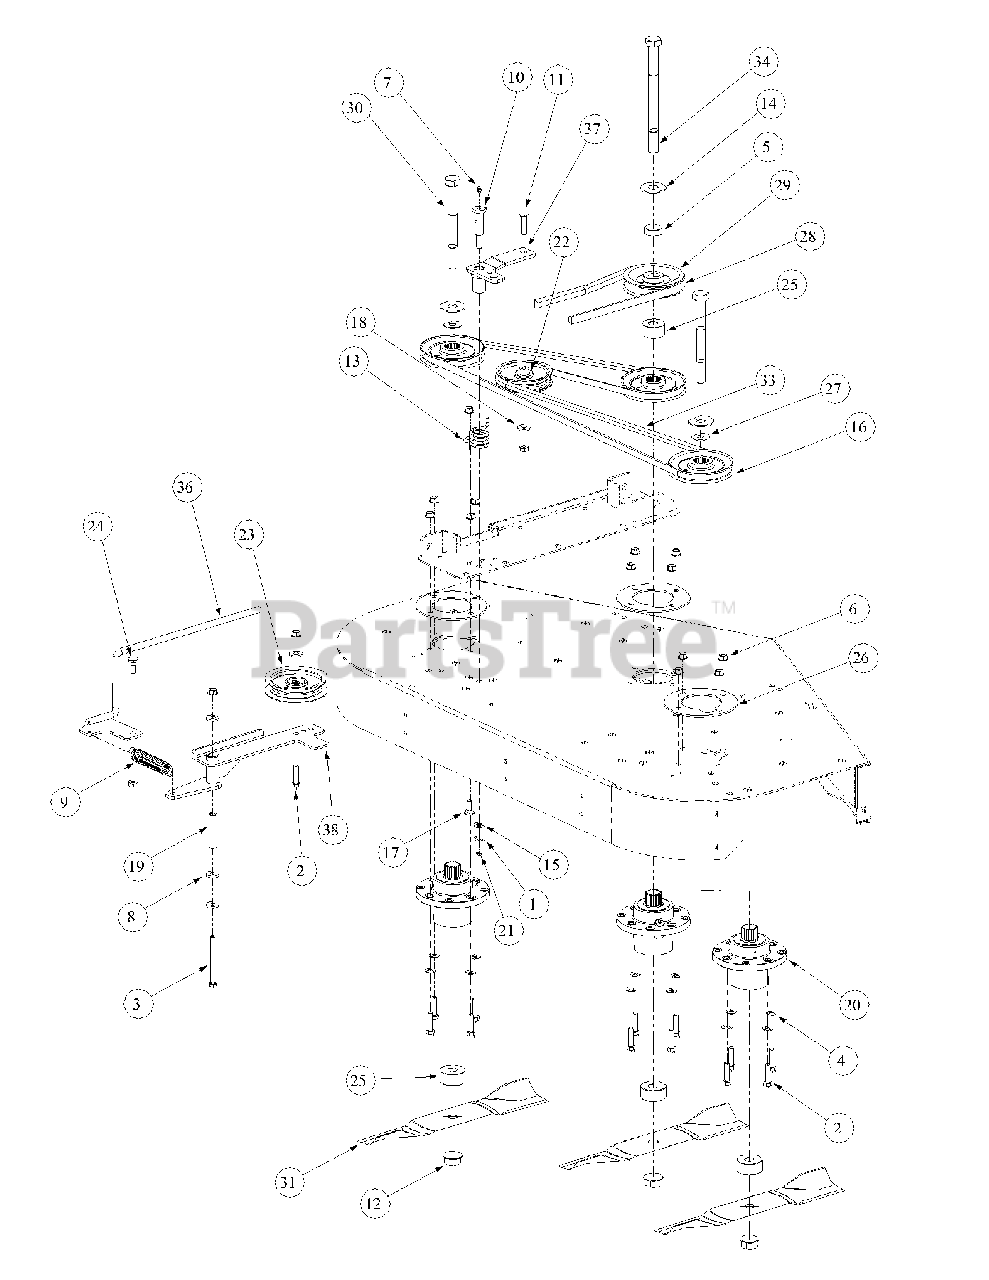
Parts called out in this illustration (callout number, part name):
1	Lock Washer, 7/16
2	Hex Cap Screw, 3/8-16 x 1-1/2
3	Hex Cap Screw, 3/8-16, 3.75
4	Flat Washer, 3/8
6	Hex Nut, Flange Lock, 3/8-16
7	Grease Fitting, 1/4-28 x 3/16
8	Idler Washer
9	Spring Extension, 1.0 OD x 5.125
10	Shoulder Screw, 7/16-14
11	Hex Carriage Screw, 3/8-16, 1.75
12	Hex Flange Nut, 3/4-16
13	Torsion Idler Spring
14	Flat Washer, .781 ID, 2.00 OD, .105
15	Flat Washer, .469 ID, .875 OD, .105
16	V-Pulley, 4.65 OD
17	Carriage Bolt, 3/8-16 x 1
18	Flat Washer, .406 ID, 1.0 OD, .105
19	Spacer, .39 ID x .625 OD x 2.75
20	Aluminum Spindle Assembly
21	Hex Nut, 7/16-14
22	Flat Pulley
23	Idler Pulley, 4.06 OD w/Deep Flange
24	Shoulder Screw, .50 x .27 Lg., 3/8-16
25	Spacer, .760 ID x 2.000 OD x 1.1
26	Spindle, Aluminum Cast Support Plate
27	Spacer, .812 ID x .268 LG
28	V-Belt, B Section x 83.2
29	V-Pulley, 4.75 OD
30	Hex Cap Screw, 3/4-16, 7.00
31	Blade, 17.0, Hi-Lift, 0.756 ID
33	V-Belt, A Section x 105.3
34	Hex Cap Screw, 3/4-16, 9.00
36	Spring Tension Rod Assembly
37	Idler Arm Assembly, Deck Spindle
38	Idler Arm Assembly, Flat Top Bearing
